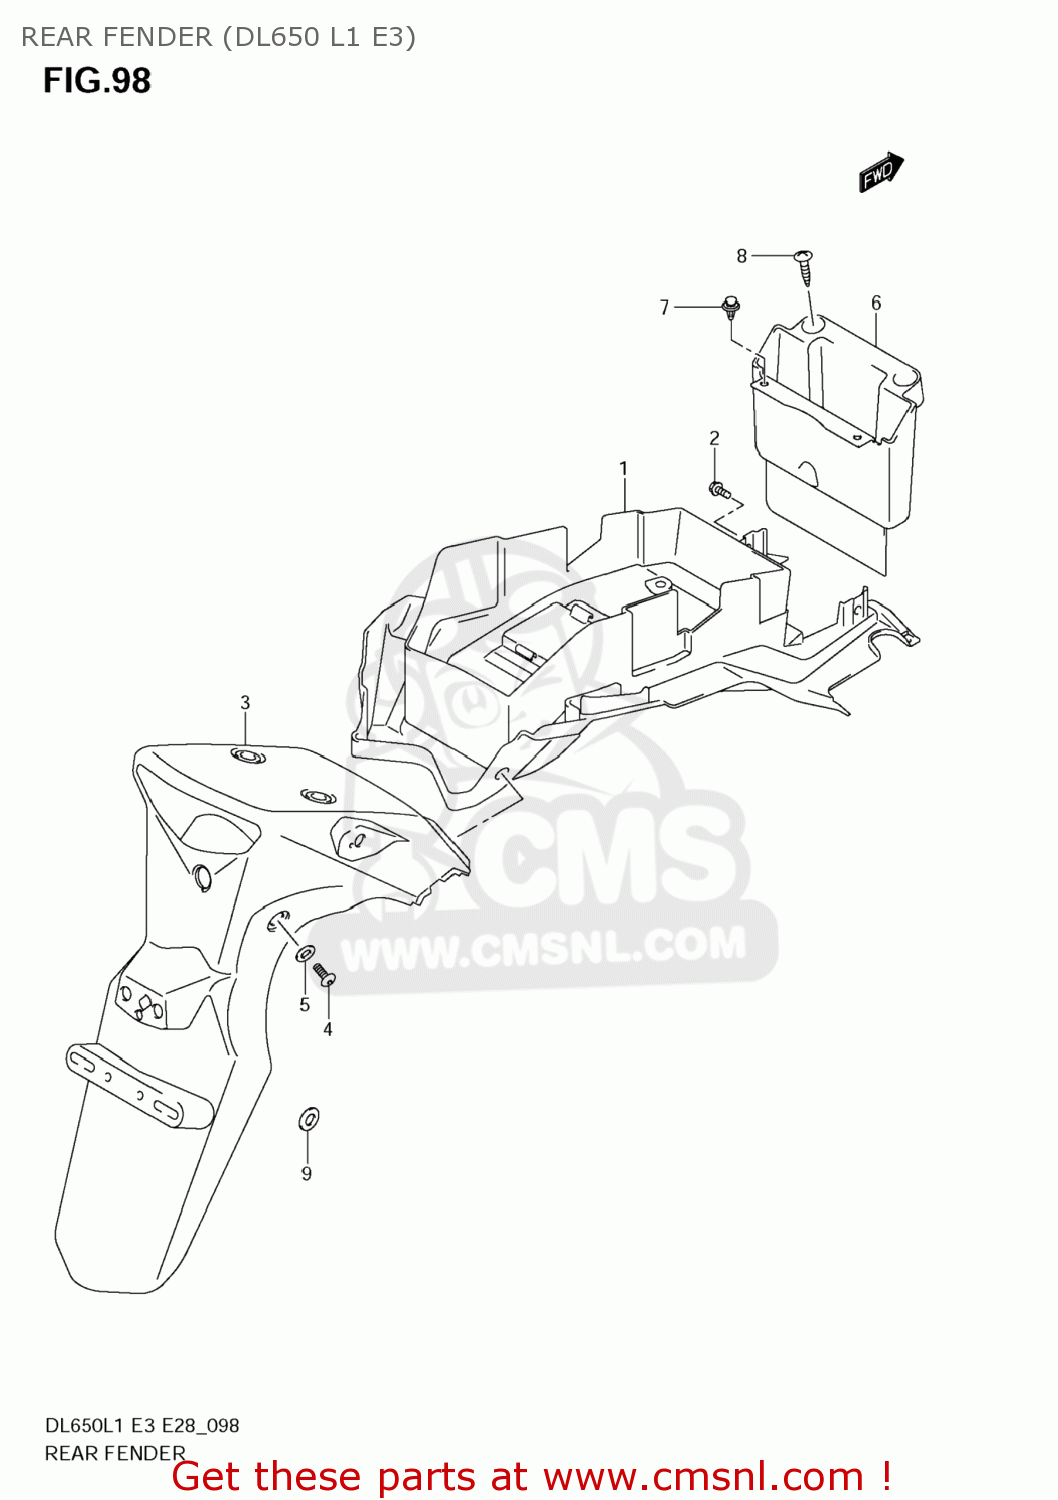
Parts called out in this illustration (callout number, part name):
1	FENDER,RR
2	BOLT(6X12)
3	FENDER,RR RR
4	SCREW(6X16)
5	WASHER(6.5X18X1.6)
6	COVER,RR FENDER LWR
7	CLIP(BLACK)
8	SCREW
9	WASHER
